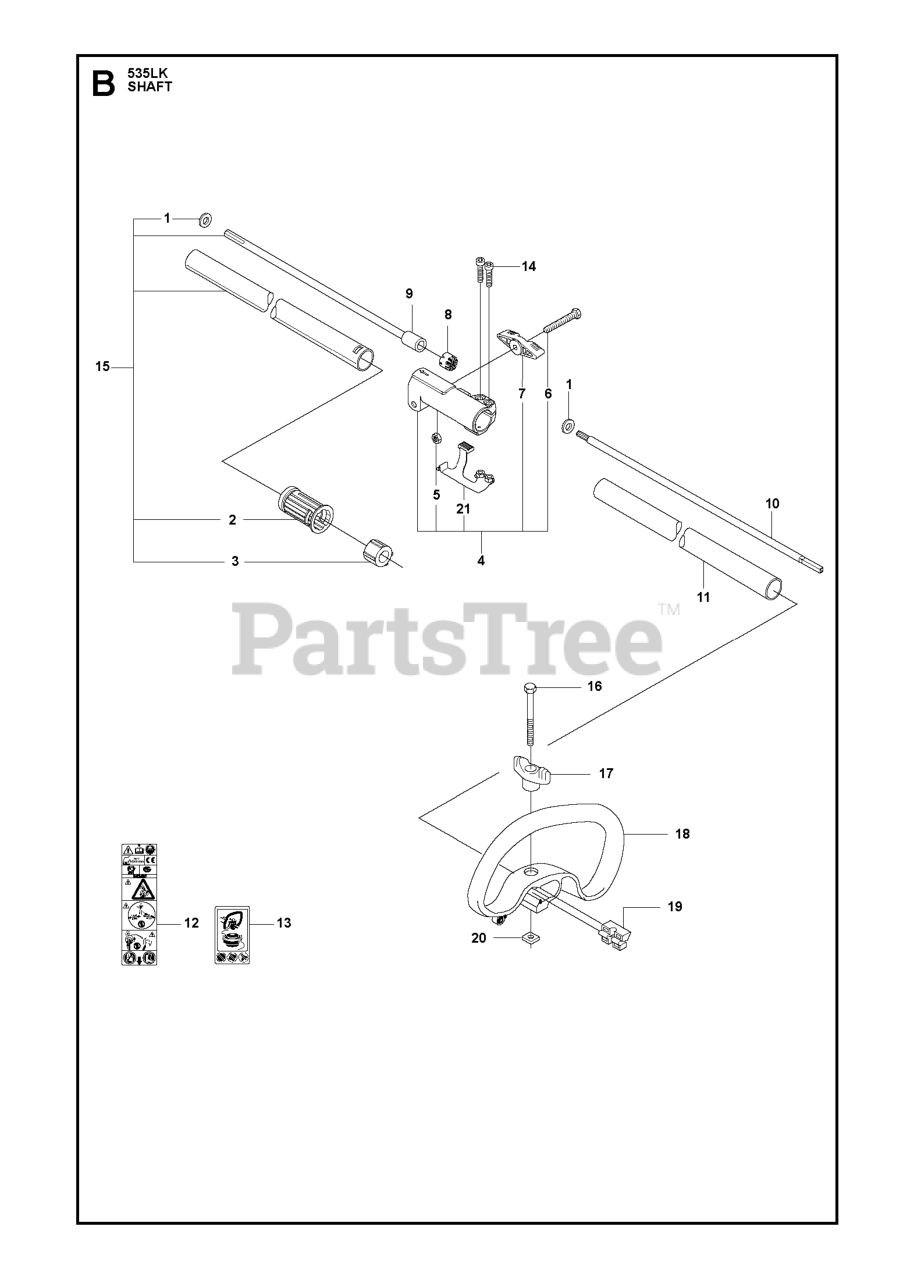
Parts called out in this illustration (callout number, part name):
4	CLAMPING SLEEVE
6	SCREW
7	KNOB CLAMPING SLEEVE
9	SHAFT
10	DRIVE SHAFT
11	TUBES
12	LABEL WARNING TRIMMERS AND BRU
13	DECAL WARNING "NO BLADES"
16	SCREW M6X50
18	HANDLE, LOOP
19	SPACER PLASTIC
21	LOCKING PLATE ASSY CLAMPING SL
